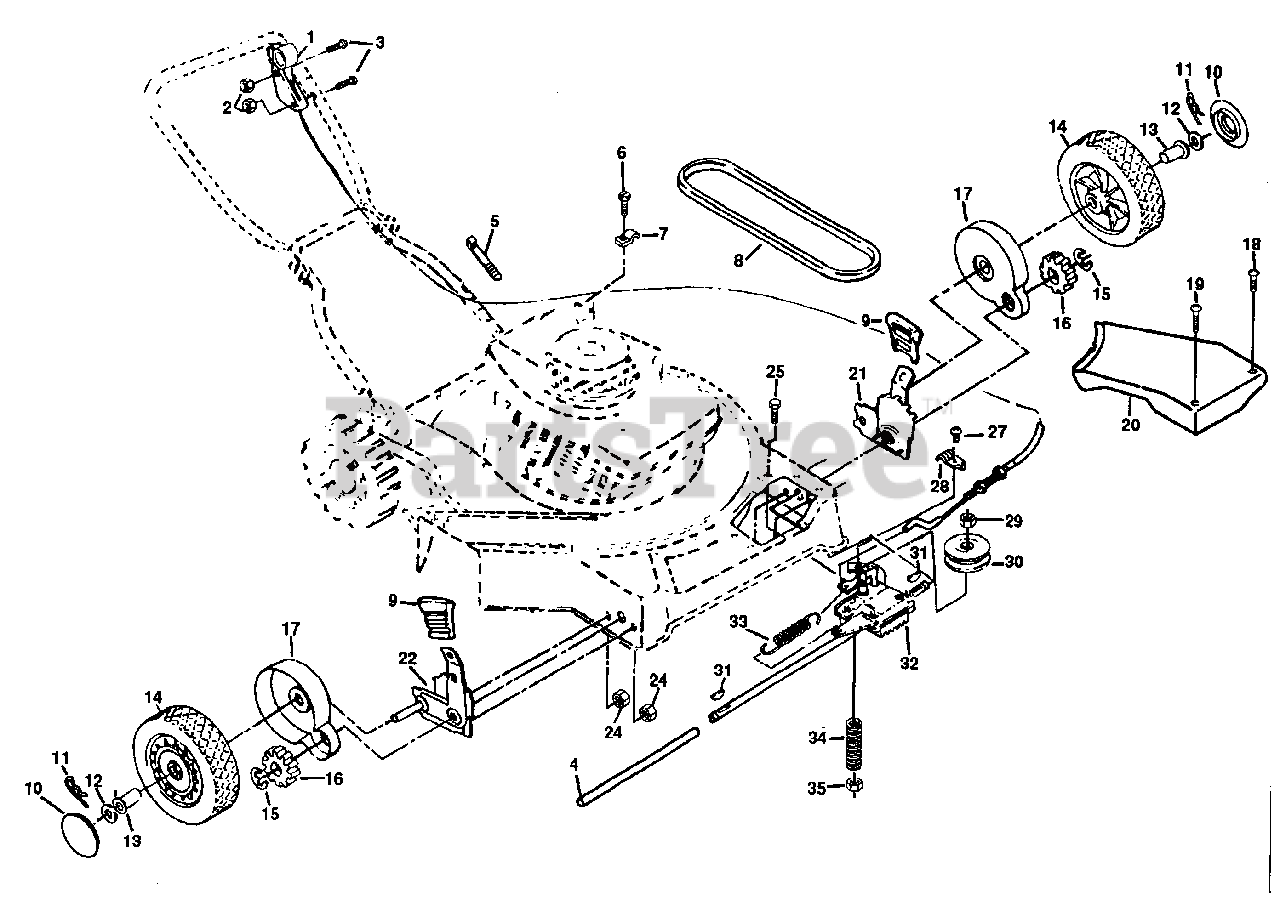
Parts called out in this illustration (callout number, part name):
1	Drive Control Cable (AYP part number)
2	Locknut (AYP part number)
3	Machine Screw #10-24 x 2 (AYP part number)
4	Drive Shaft Cover (AYP part number)
5	Wire Tie (AYP part number)
6	Hex Washer Head Screw #10-24 x 1/2 (AYP part number)
7	Cable Guide Clip (Housing) (AYP part number)
9	Selector Knob
10	Hubcap (AYP part number)
11	Retainer Clip (AYP part number)
12	Washer (AYP part number)
13	Wheel Bushing (AYP part number)
14	Wheel & Tire Assembly (Front) 8.00 x 1.75
15	External E-Ring
16	Pinion (AYP part number)
17	Dust Cover (AYP part number)
18	Pan Head Machine Screw #10-24 x 1-3/4 (AYP part number)
19	Pan Head Machine Screw #10-24 x 2-3/4 (AYP part number)
20	Drive Cover (AYP part number)
21	Wheel Adjusting Assembly (Left) (AYP part number)
22	Wheel Adjusting Assembly (Right) (AYP part number)
24	Locknut 1/4-20 (AYP part number)
25	Hex Head Bolt 1/4-20 x 2-3/4 (AYP part number)
27	Screw #10-24 (AYP part number)
28	Cable Clamp (Adj. Bracket) (AYP part number)
29	Flanged Locknut 3/8-16 Zinc (AYP part number)
30	Drive Pulley (AYP part number)
31	Woodruff Key #3 (AYP part number)
32	Gear Case Assembly (AYP part number)
33	Spring (AYP part number)
35	Locknut 1/4-20 (AYP part number)
